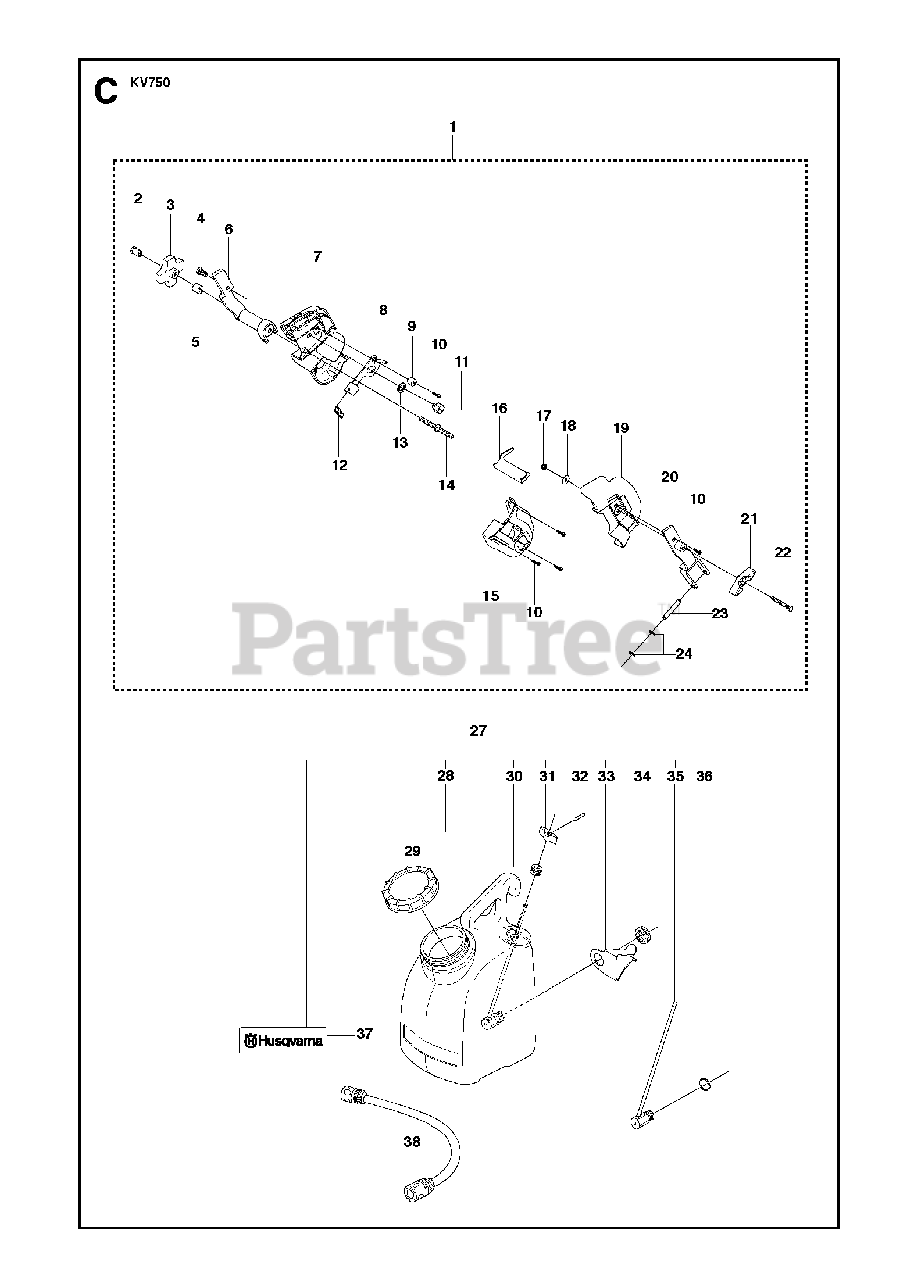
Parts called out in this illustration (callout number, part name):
1	HOLDER ASSYIncl. 2 - 23
4	SCREW EHHM
5	SPACING SLEEVE
17	HEXAGON LOCKING NUT
27	WATER TANKIncl. 28, 30 - 37
30	ANTIVIBRATION ELEMENT
